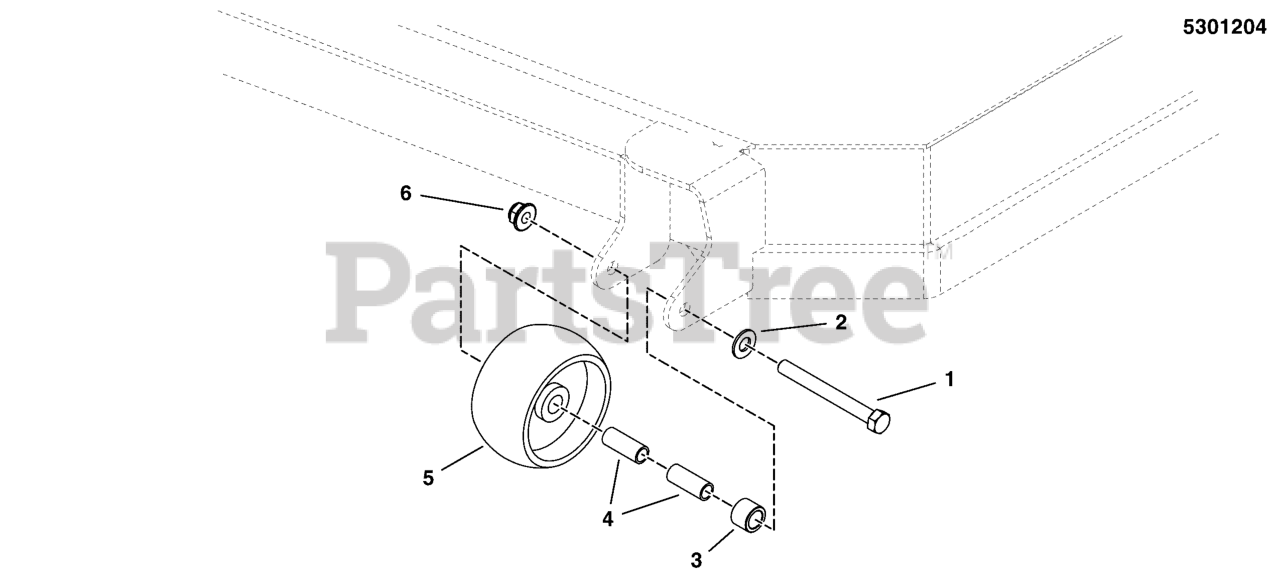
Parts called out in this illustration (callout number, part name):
1	BOLT, 3/8-16 X 3-1/2" GD5 CZ
2	WASHER, 3/8 SAE
3	SPACER, .51 X .75 X .56, CZ
4	SPACER, .38 X .50 X 1.25, CZ
5	WHEEL- 2.00 WIDE 3.88 DIA 0.531ID POLY
6	NUT, 3/8-16 HEX NYLOCK FLANGE
